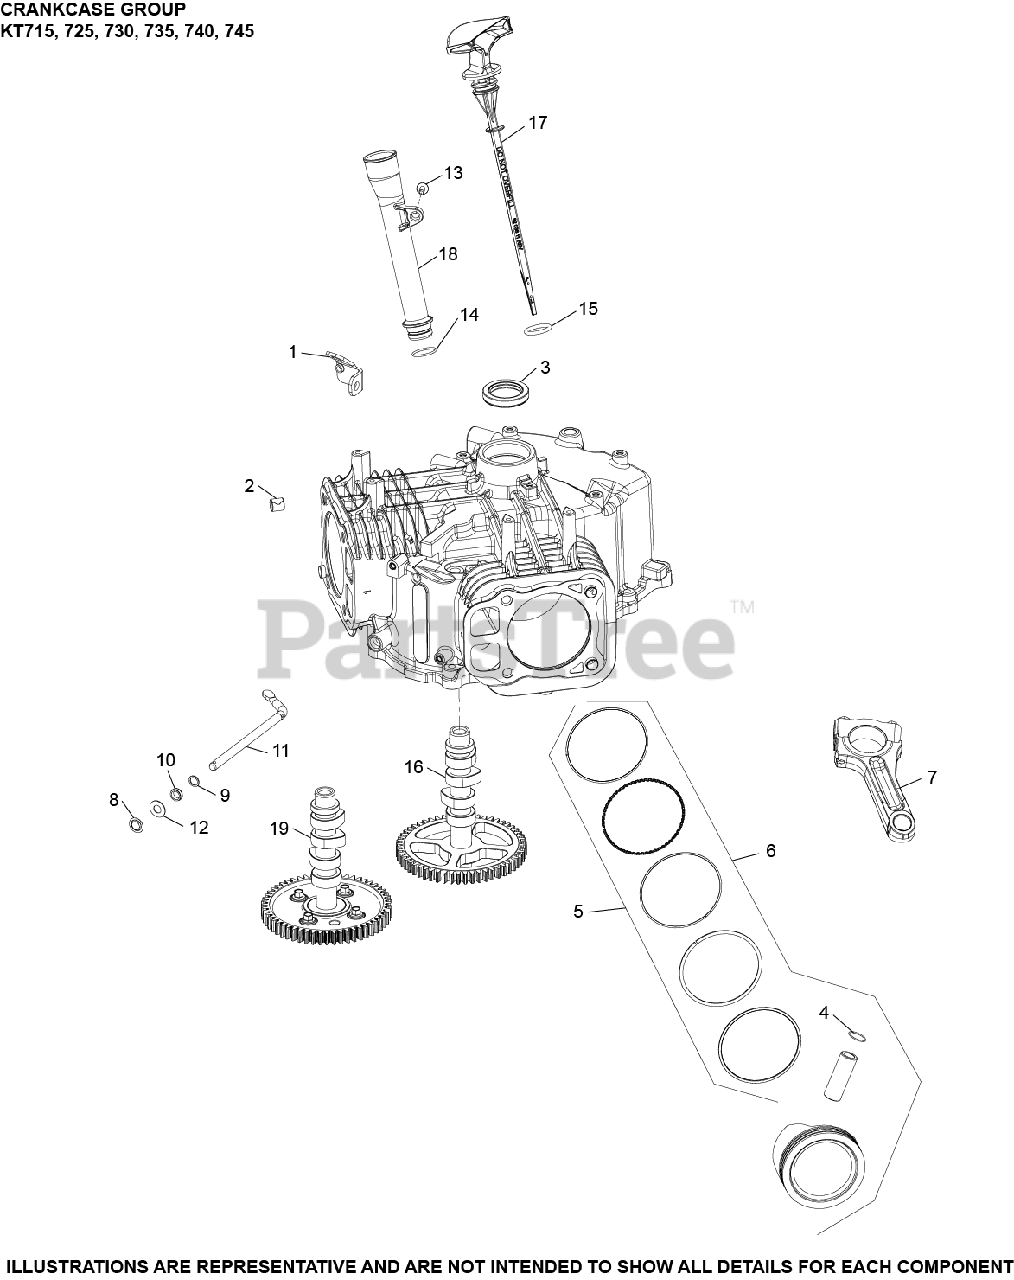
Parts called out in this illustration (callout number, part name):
1	BRACKET, OIL FILL TUBE
2	PIN, LOCATING
3	SEAL, OIL (HELIX LIP)
4	RETAINER, PISTON PIN
5	RING SET(STD)STYLE B-1.2mm Tp RING THICK
5	RING SET(.08)STYLE B-1.2mm Tp RING THICK
5	RING SET(.25)STYLE B-1.2mm Tp RING THICK
5	RING SET(.50)STYLE B-1.2mm Tp RING THICK
6	PISTON W/RINGS (STYLE B)(STD) - RING SET 25 108 01-S
6	PISTON W/RINGS (STYLE B)( 0.08) - RING SET 25 108 02-S
6	PISTON W/RINGS (STYLE B)(0.25) - RING SET 25 108 03-S
6	PISTON W/RINGS (STYLE B)(0.50) - RING SET 25 108 04-S
7	ROD, ASSY CONNECTING (STD)-(#2406730S)
7	ROD ASSY, CONNECTING U/S (.010”) (.25 mm) -USE 24 067 31-S
8	RETAINER, RING
9	WASHER, FLAT 11/32"
10	SEAL, GOVERNOR CROSS SHAFT
11	SHAFT, GOVERNOR CROSS
12	WASHER, FLAT 9 MM
13	SCREW, THREAD FORMING
16	CAMSHAFT ASSEMBLY
17	DIPSTICK ASSEMBLY USE 32 038 14-S
18	TUBE ASSEMBLY, OIL FILL
